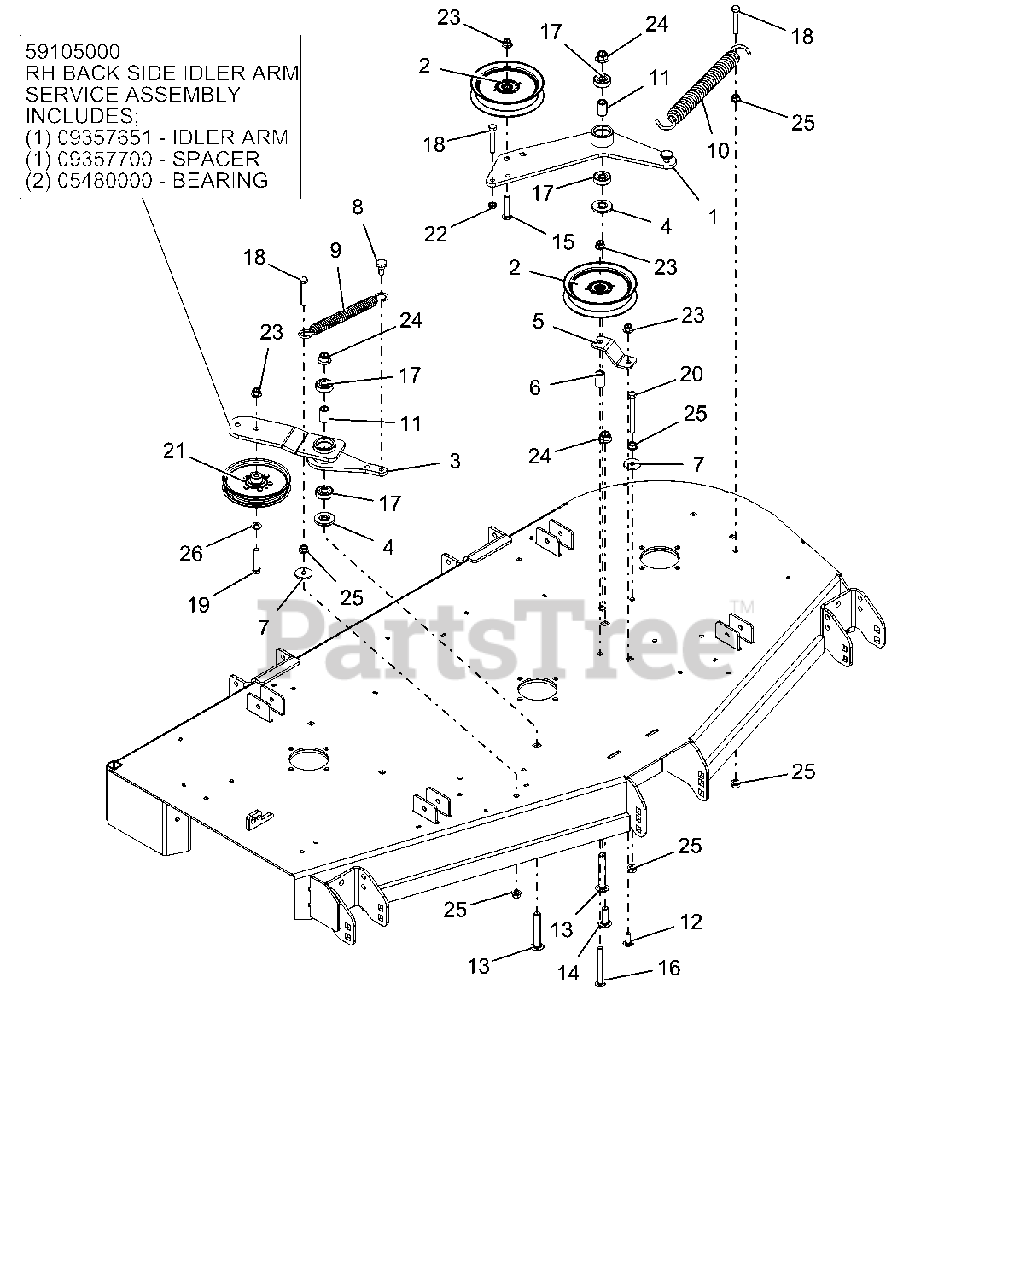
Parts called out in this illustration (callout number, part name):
1	WLDMT, DECK PTO IDLER ARM (BLACK)
2	IDLER, FLAT - 5.00" X .75"
3	WLDMT, DECK RH IDLER ARM
3	RH BACK SIDE IDLER ARM SERVICE ASSEMBLY
3	IDLER ARM
3	SPACER
3	BEARING
4	SPACER, IDLER ARM
5	BRKT, PTO FIXED IDLER MTG (RED)
6	BUSHING, SLV .380 X .750 X 1.190
7	WSHR-FL-STL .406X1.375X.135 YZ
8	BLT, SHLDR EP .38-16X.30 HEX YZ
9	SPRG, EXTENSION - SWIVEL
10	SPRG, EXTENSION
11	SPACER, .510 X .750 X 1.148
12	BLT-RDHDSHSQNK.38-16X1.0 G5YZ
13	BLT-RDHDSQSHNK .50-13X3.25 YWZC
14	BLT-RDHDSQSHNK .50-13X1.50 YWZC
15	BLT-RHDSSQNK .38-16X2.00 G5YZ
16	BLT-RHDSSQNK .38-16X3.50 G5YZ
17	BRG-BALL .500X1.375X.44
18	BLT-HEX .38-16X2.25 GR5 YWZC
19	BLT-HEX .38-16X2.00 GR5 YWZC
20	BLT-HEX .38-16X3.50 GR5 YWZC
21	PULLEY, FLAT IDLER .500 X .375 W/BRG
22	NUT, JAM .375-16 YWZC
23	NUT-LK-NYL-FLG .38-16 YWZC
24	NUT-LK-NYL-FLG .50-13 YWZC
25	@NUT-SPNLK-FLG .375-16 YWZC
26	WSHR-FL-STL.406X.812X.065 YWZ
